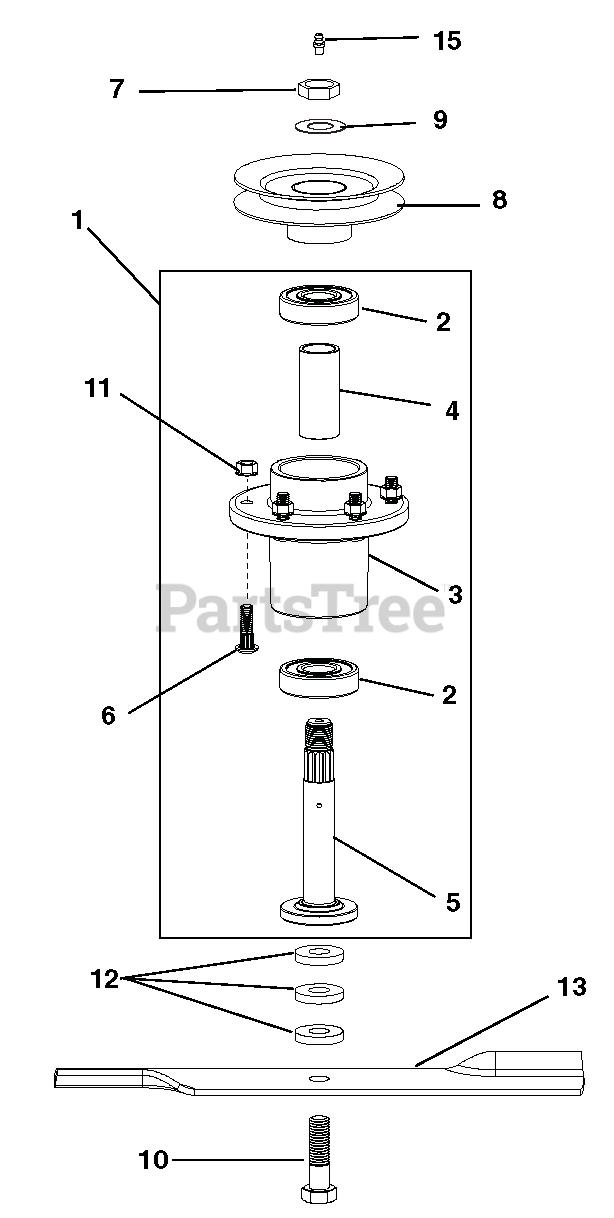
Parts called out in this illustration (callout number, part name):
1	ASSY, SPINDLE HOUSING
2	BEARING, 6305LLC
3	HOUSING, SPINDLE W/STUDS
4	SPACER, 1.250X1.000X2.780
5	SHAFT, SPINDLE 3/4-16
6	BOLT, 3/8-16X1.25RDHD RIBNKS/O
7	LOCKNUT, 3/4-16 CROWN PL
8	Pulley, Cutter Housing
9	WASHER, .75X1.3125X.120
10	BOLT, 5/8-11 X 2.00 HEX 8 Y
11	NUT, 3/8-16 STD HEX GR5 Y
12	WASHER, .630X1.50X.250 FLAT Y
13	BLADE, 18.000 X .80 LIFT
14	BLADE, 16.500 X .80 LIFT
15	FTG, 1/4-28 STRGT GREASE ZERK
